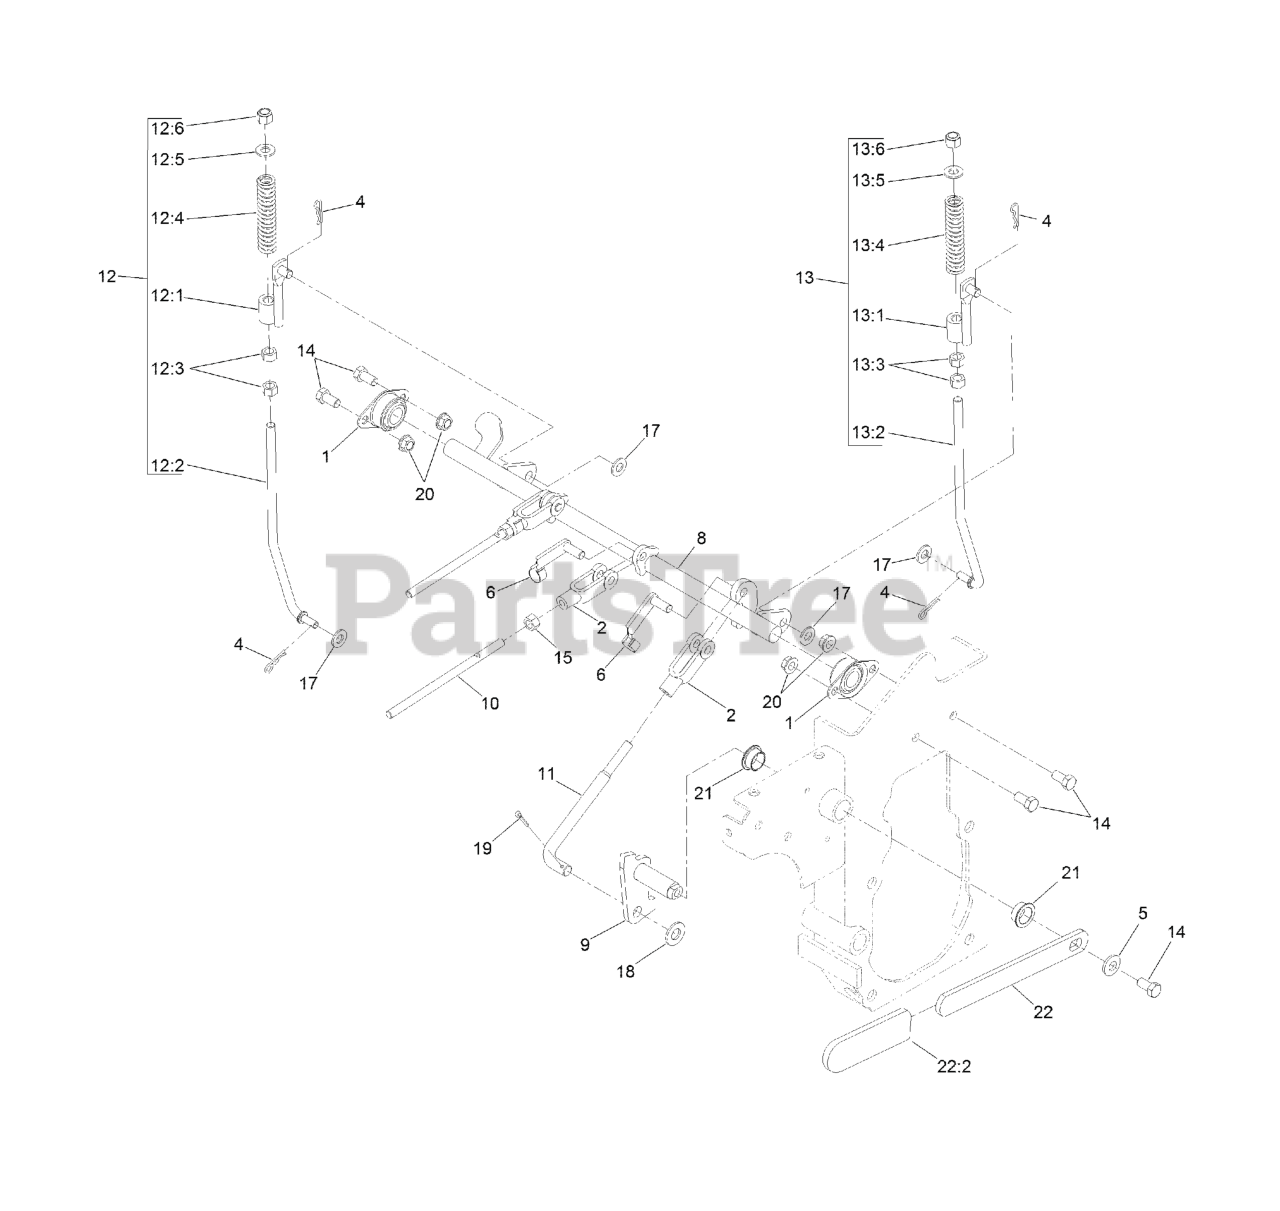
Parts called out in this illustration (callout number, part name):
1	BEARING-FLANGE, SIDE
2	YOKE-LINKAGE, BRAKE
4	PIN-COTTER
5	WASHER-BELLEVILLE
6	PIN-SPRING, CLEVIS
8	SHAFT-BRAKE
9	PIVOT-BRAKE
10	ROD-LINKAGE, BRAKE
11	ROD-LINKAGE, BRAKE
12	RH BRAKE LINKAGE ASM
12:1	BRAKE LINKAGE ASM
12:2	LINK-BRAKE, RH
12:3	NUT-HEX
12:4	SPRING-COMPRESSION
12:5	WASHER-FLAT
12:6	NUT-LOCK
13	LH BRAKE LINKAGE ASM
13:1	BRAKE LINKAGE ASM
13:2	LINK-BRAKE, LH
13:3	NUT-HEX
13:4	SPRING-COMPRESSION
13:5	WASHER-FLAT
13:6	NUT-LOCK
14	SCREW-HH
15	NUT-HEX
17	WASHER-FLAT
18	WASHER-FLAT
19	PIN-COTTER
20	NUT-HHF, WHIZ
21	BUSHING-BRONZE
22	PARK BRAKE HANDLE ASM
22:2	GRIP-LEVER
